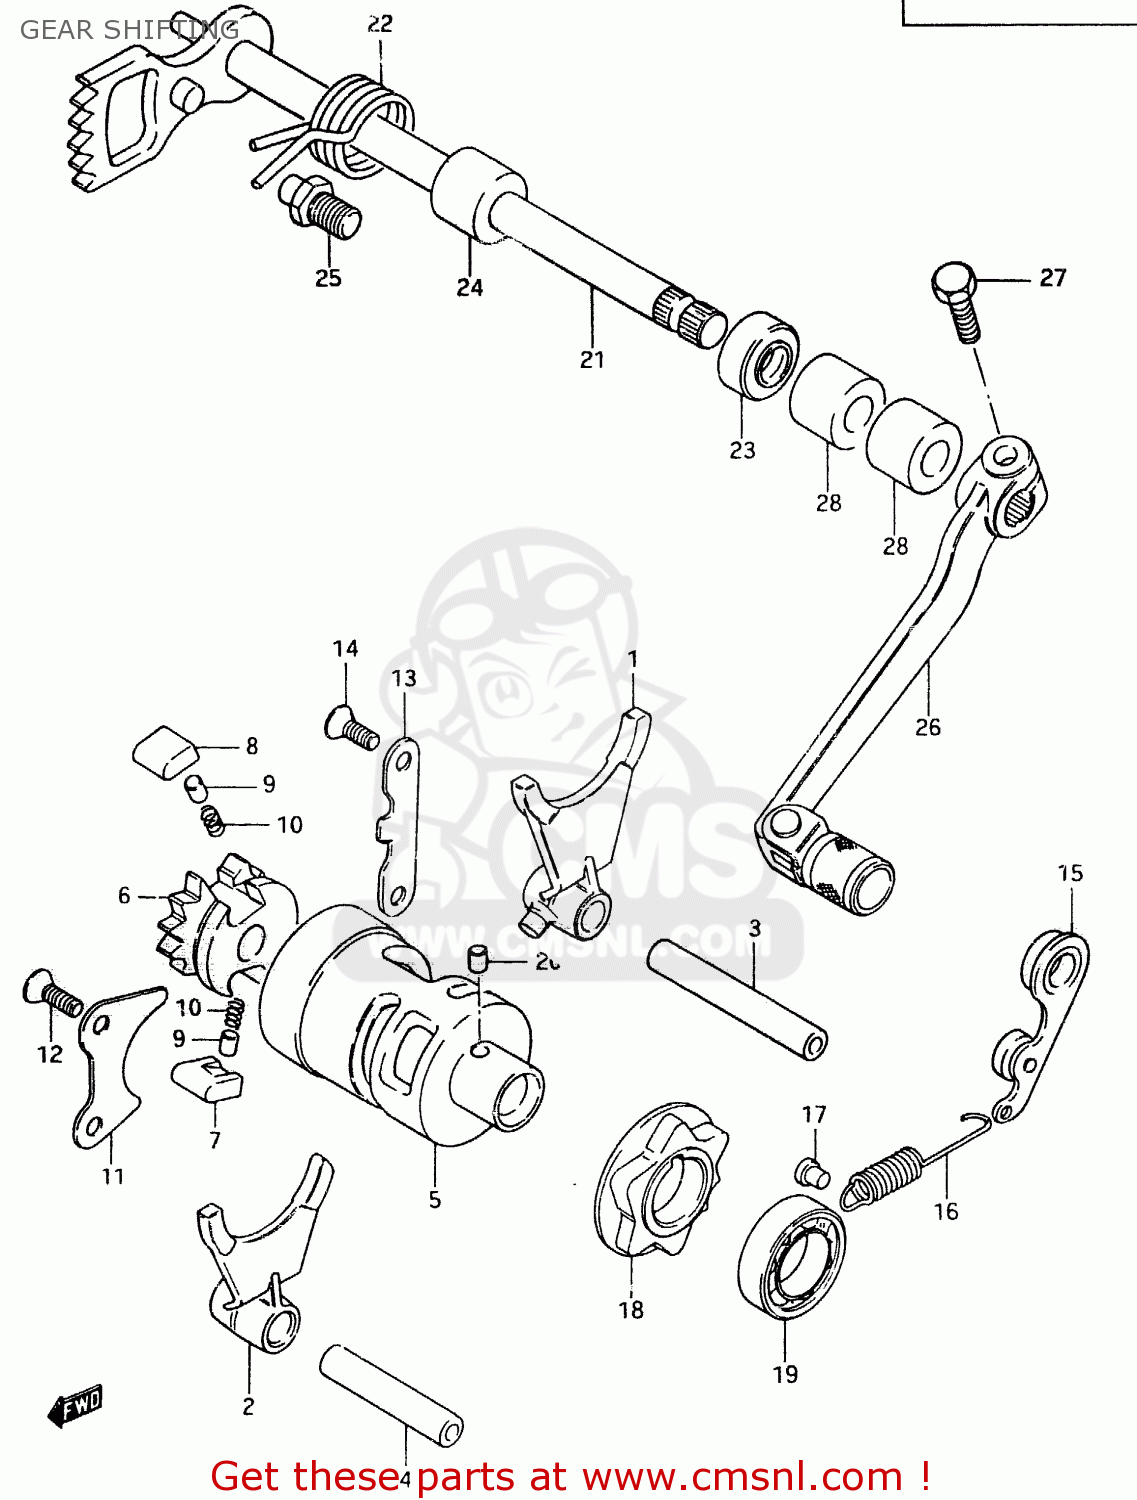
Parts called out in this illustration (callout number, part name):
1	FORK,GEAR SHIFT NO.1
2	FORK,GEAR SHIFT NO.2
3	SHAFT,GEAR SHIFT FORK
4	SHAFT,GEAR SHIFT FORK
5	CAM,GEAR SHIFT
6	RETAINER,GEAR SHIFT CAM
7	PAWL,GEAR SHIFT NO.1
8	PAWL,GEAR SHIFT NO.2
9	PIN(5X8)
10	SPRING
11	LIFTER,GEAR SHIFT PAWL
12	SCREW
13	STOPPER,GEAR SHIFT POLE
14	SCREW
15	STOPPER,GEAR SHIFTING
16	SPRING
17	RIVET
18	PLATE,GEAR SHIFT CAM STOPPER
19	BEARING
20	PIN
21	SHAFT,GEAR SHIFT
22	SPRING
23	OIL SEAL
24	SPACER(12X20X15.3)
25	STOPPER,GEAR SHIFT CAM
26	LEVER ASSEMBLY,GEAR SHIFTING
27	BOLT
28	SPACER(12X20X15.3)
